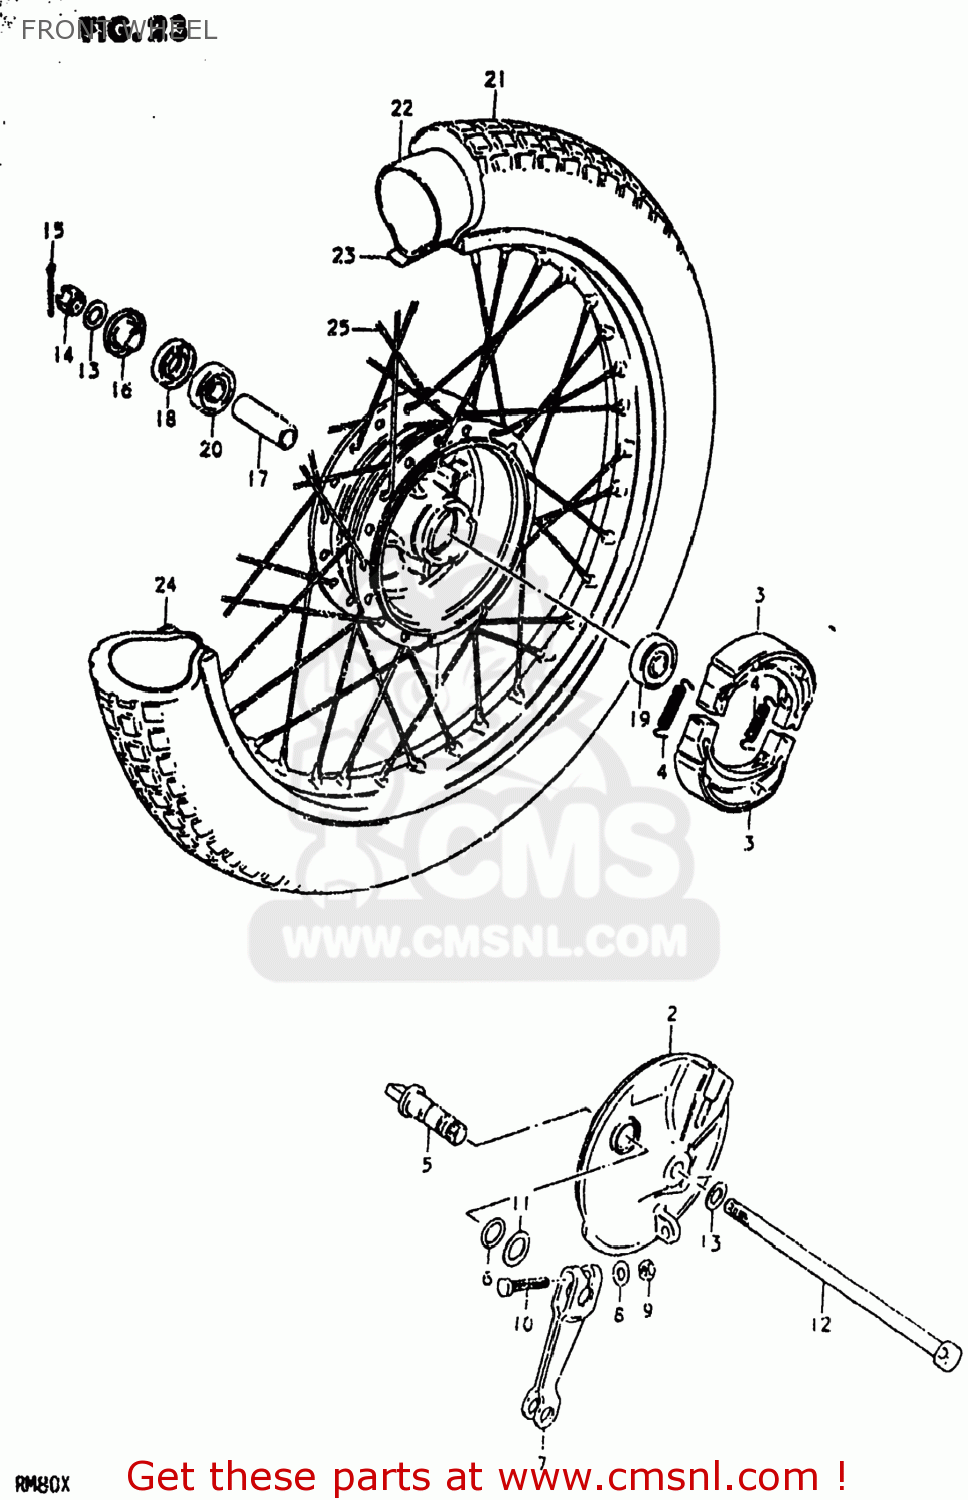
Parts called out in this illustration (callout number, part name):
1	HUB,FRONT
2	PANEL,FR BRAKE ANCHOR
3	SHOE,BRAKE (MCA)
4	SPRING(L:34)
5	CAM,FRONT BRAKE
6	O-RING (D:2.4 ID:13.8)
7	LEVER,FR BRAKE CAM
8	WASHER
9	NUT
10	BOLT(6X33)
11	WASHER (14.5X22X1.6)
12	AXLE,FRONT
13	WASHER
14	NUT
15	PIN 20X20
16	SPACER,FRONT AXLE,RIGHT
17	SPACER (10.2X16X51)
18	SEAL,OIL(15X31X5)
19	BEARING
20	BEARING
21	TIRE,FRONT
22	TUBE,INNER
23	PROTECTOR,WHEEL,INNER
24	RIM,FRONT WHEEL (1.40X17)(
25	SPOKE SET,FRONT
